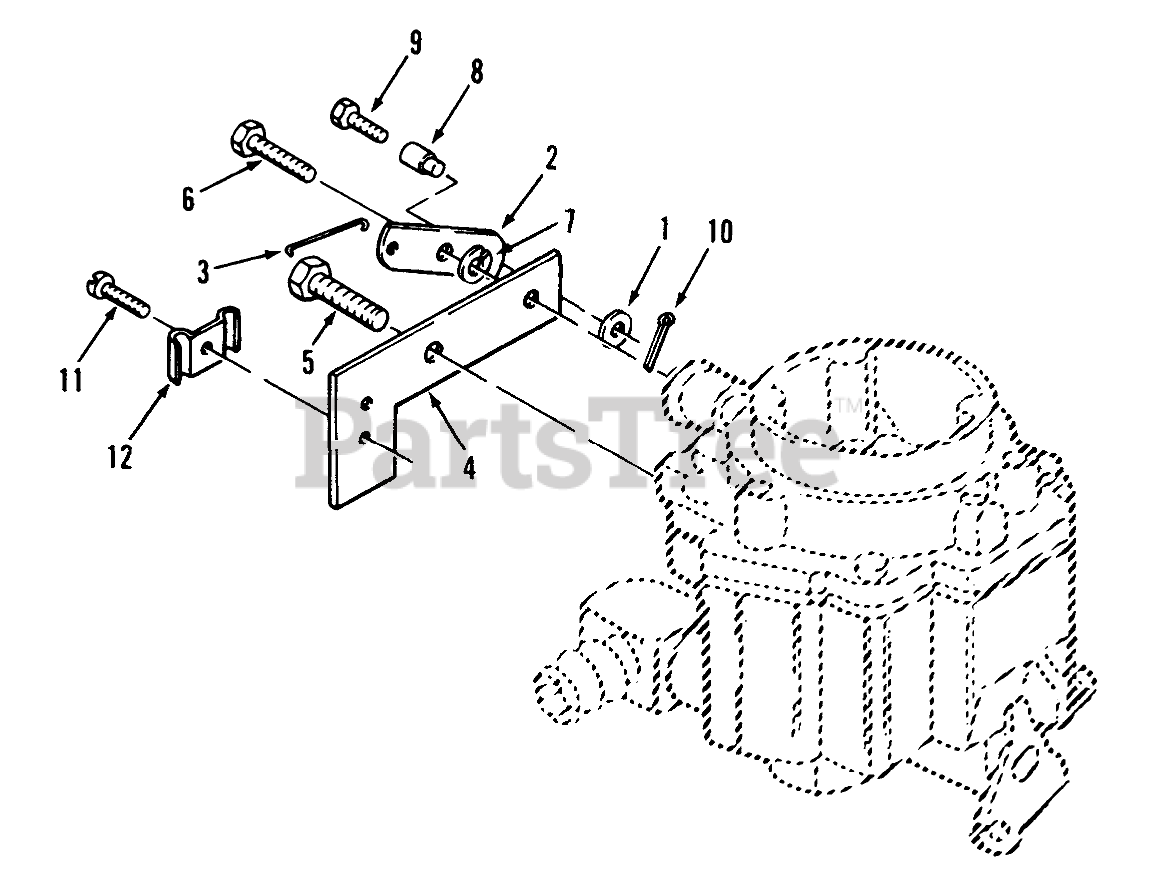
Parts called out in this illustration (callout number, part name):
1	Washer
2	SWIVEL-CHOKE
3	LINK-CHOKE
4	BRACKET
5	SCREW-HWH
6	BOLT-SHOULDER
7	WASHER-LOCK
8	SWIVEL
9	SCREW
10	PIN-COTTER
11	SCREW-TAPPING
